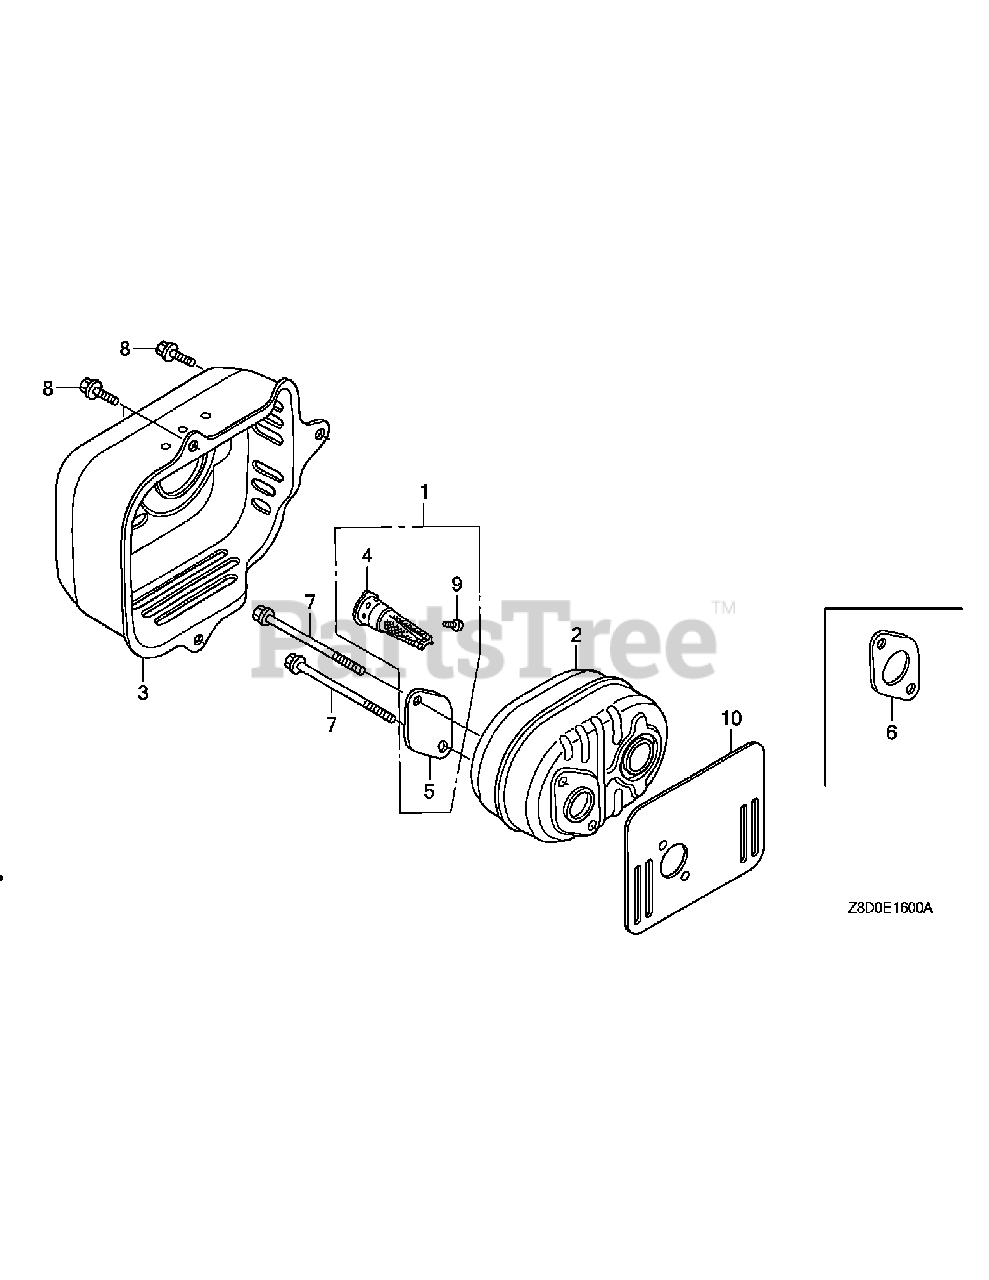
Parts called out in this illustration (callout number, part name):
1	Spark Arrester Kit
2	Muffler Complete
3	Muffler Protector
4	Spark Arrester Complete
5	Arrester Number Plate
6	Muffler Gasket
7	Flange Bolt, 6 x 79
8	Flange Bolt, 6 x 12
9	Tapping Screw, 4 x 6
10	Muffler Gasket
